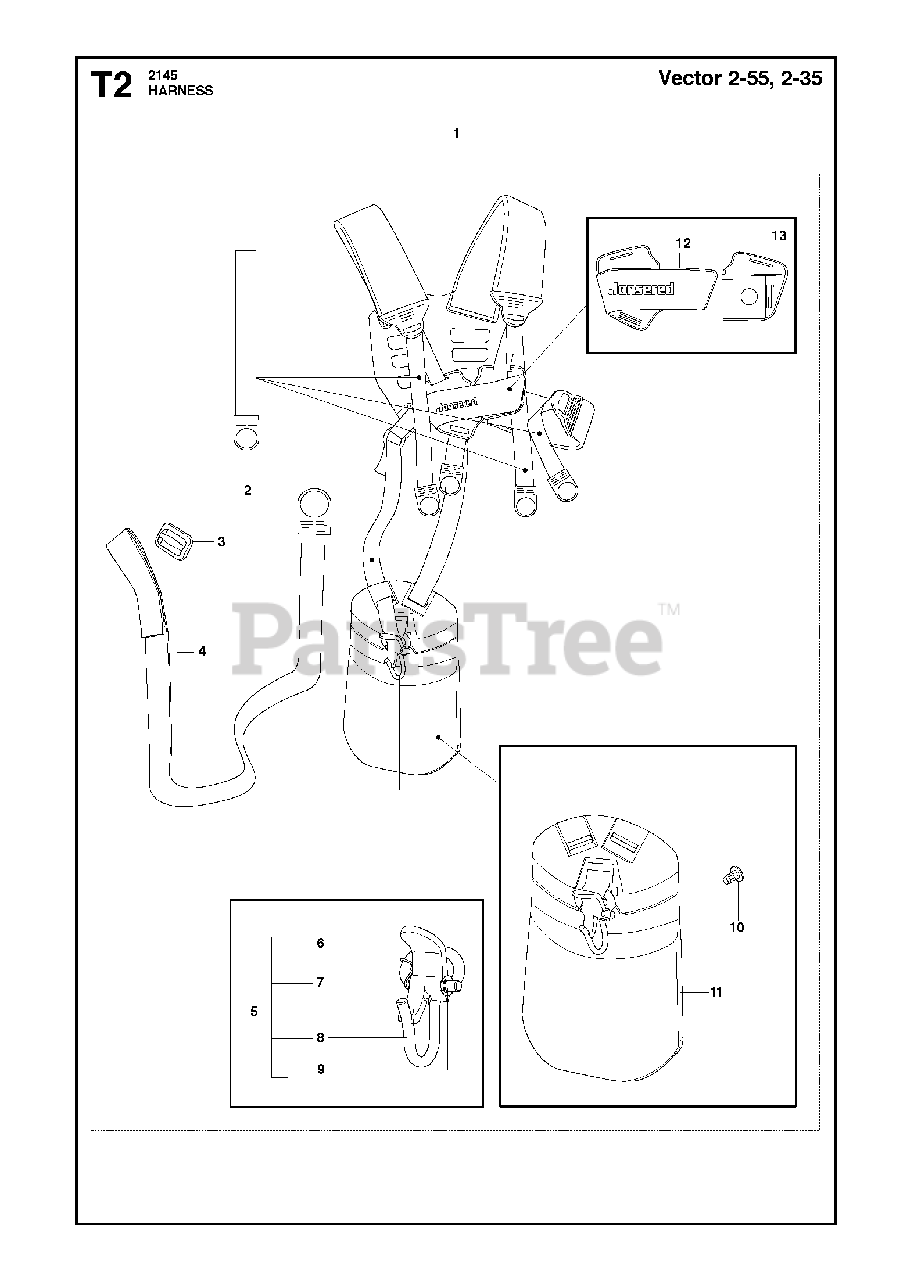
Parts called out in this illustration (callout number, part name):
1	HARNESS "VECTOR" 2-55
1	HARNESS COMPLETE
2	BAND
3	CLIP
4	BAND
5	HARNESS HOOK, COMPLETE
6	CATCH *
7	SPRING
8	HOOK
9	E-RING 5
10	RIVET
11	PROTECTOR
12	FRONT PIECE
13	FRONT PIECE
